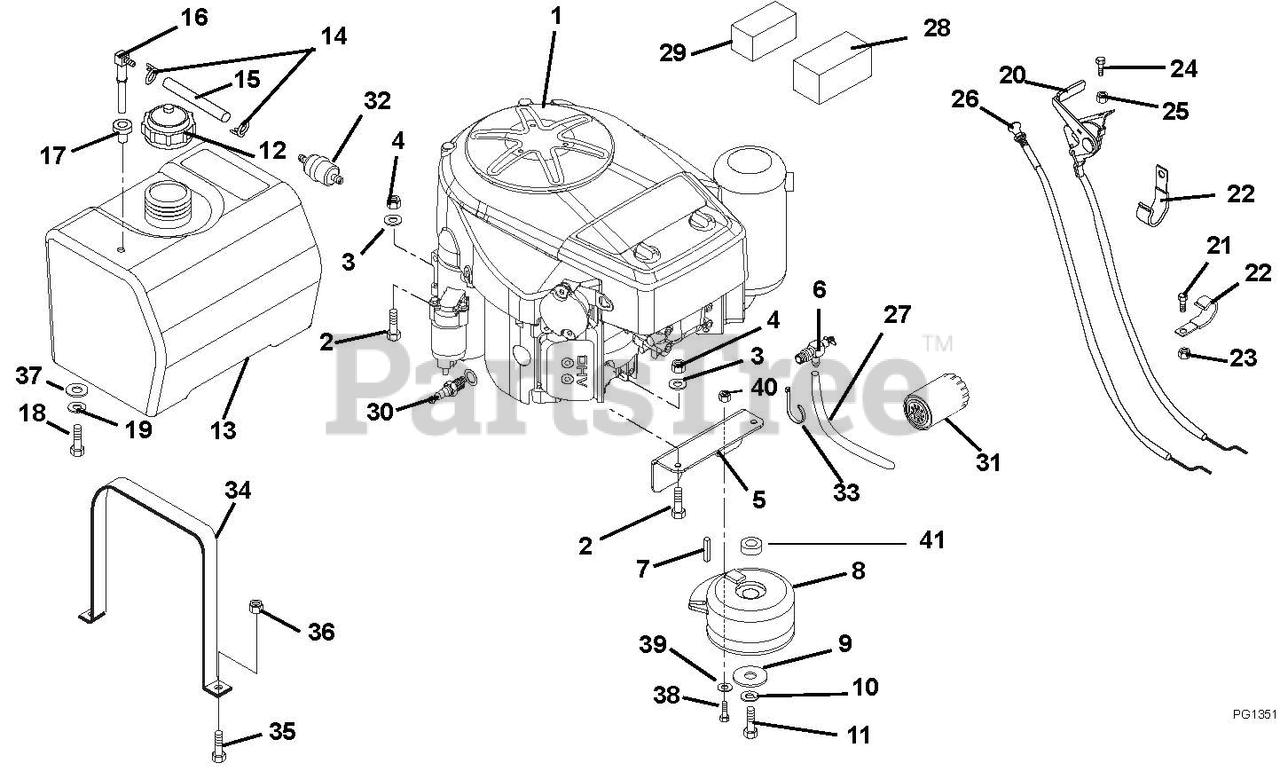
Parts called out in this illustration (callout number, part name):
1	Engine, 15 HP Kawasaki FH430V - AS02
1	Engine, 13 HP Kawasaki FH381V-AS02
1	Engine, 13 HP Kawasaki CA FH381V-AS02
2	Bolt, Hex .31-18 x 1.75 Grade 5
3	Washer, Locking .31 x .078 Regular
4	Nut, Hex .31-18
5	Bracket, Clutch
6	Valve, Oil Drain
7	Key, Square .25 x 1.25 x 25 SAE 8630 or SAE 1035
7	Key, Square .25 x .25 x 1.00 RC 40-50
8	Clutch, Electric PTO
9	Washer, Flat-Steel .469 x 2.00 x .25
10	Washer, Locking .44 x .109 Regular
11	Bolt, Hex .44-20 x 3.00 Grade 5
11	Bolt, Hex .44-20 x 2.50 Grade 5
12	Cap, Fuel
13	Tank, Fuel
14	Clamp, Hose Wire .49/.51 x .116
15	Gas Line, Bulk .25 I.D.
16	Fitting, Tank
17	Bushing
17	Grommet
18	Bolt, Hex .38-16 x .75 Grade 5
19	Washer, Locking .38 x .094 Regular
20	Cable, Throttle with Liner
21	Bolt, Hex .31-18 x .75 Grade 5
23	Nut, Locking-Nylon .312-18
24	Screw, Machine 10-24 x .75 Hex Washer Head
25	Nut, Locking-Nylon 10-24 with Insert
26	Control, Choke
27	Tube, Oil Drain
28	Filter, Air Paper
29	Filter, Air Foam
30	Spark Plug
31	Filter, Oil
32	Fuel Filter, Kawasaki
33	Cable Tie
34	Tank Strap
35	Bolt, Round Head Square Neck .25-20 x .75 Grade 5
36	Nut, Locking Nylon .25-20
37	Washer, Flat Steel .409 x .812 x .065
38	Bolt, Hex .312-18 x 2.00 FTH Grade 5
39	Washer, Flat-Steel .344 x .688 x .065
40	Nut, Jam .31-18
41	Bushing, Spacer 1.0 x 1.25 x .25
